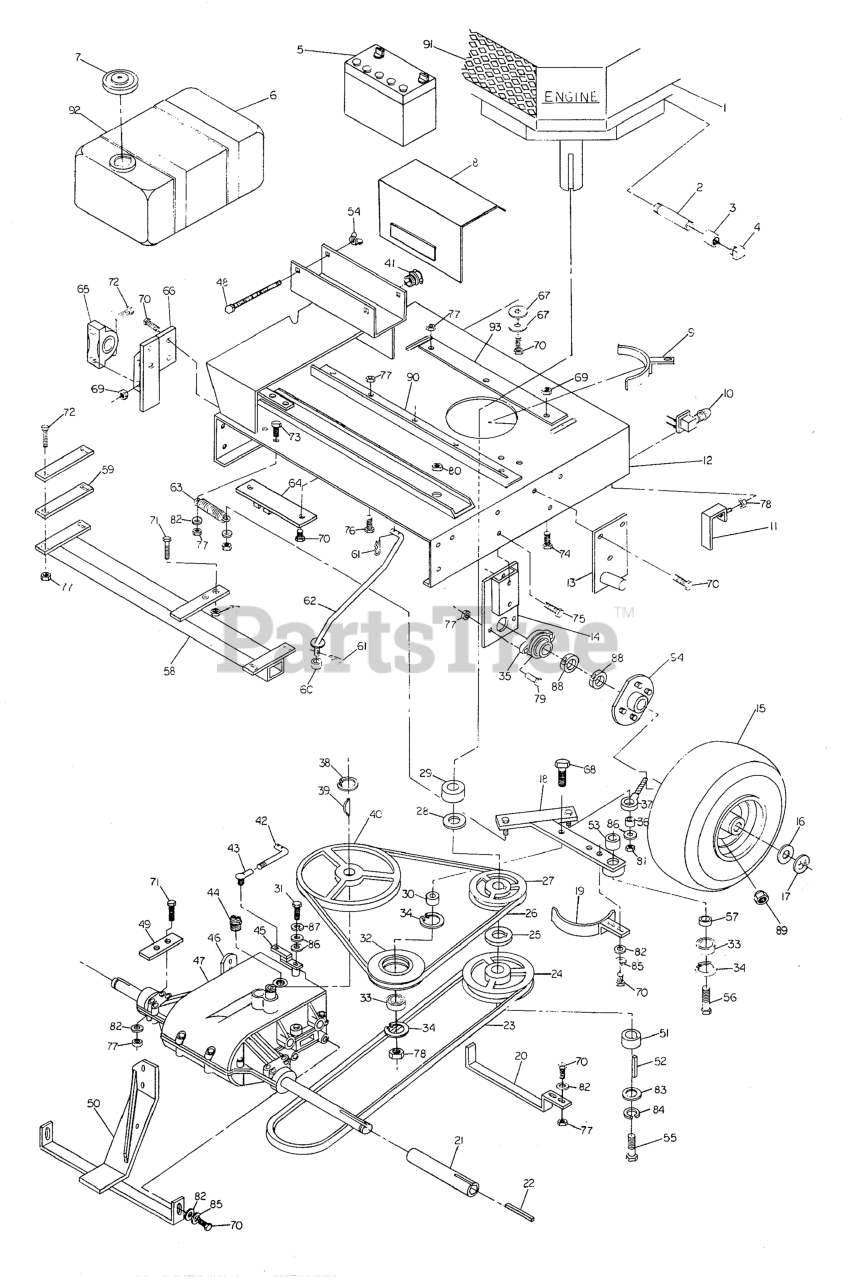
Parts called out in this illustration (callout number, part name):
1	ENGINE, 18HP Briggs & Stratton
2	Oil Drain Extension Kohler 5"
2	Oil Drain Extension
3	Coupler
4	Pipe Plug
5	BATTERY, 11U1L, 350 CCA
6	Fuel Tank, 4 Gallon
7	Gas Cap
8	Battery Cover
9	ENGINE BELT GUIDE
10	Safety Switch
11	Engine Deck Belt Keep Weldment
12	Engine Deck Weldment
13	Pivot Bracket - LH
14	Long Axle Bearing Mount Weldment
15	Drive Tire Assembly (Tire & Rim)
15	Tire Only
15	Rim Only
15	DRIVE HUB
16	SHIM
17	C-CLIP
18	Idler Arm Weldment
19	Idler Pulley Belt Guide
20	Belt Guide
21	Long Axle Support
22	KEY, 3/16" SQ. X 2-1/2
23	BELT, B Section
24	ENGINE PULLEY
25	1/8" Spacer
26	Belt A Section
27	ENGINE PULLEY
28	SHIM, 1.0 X 1.5 X 0.125
29	Engine Spacer
30	SPACER, Shoulder
31	1/4-28 x 5/8 Bolt
32	Idler Pulley Clutch
33	BEARING, BALL 11/16X1-9/16X15/32
34	SNAP RING, Internal
35	Bearing
36	Cable Spacer
37	Clutch Cable
38	RING, External, Snap
39	Hy Pro Key
40	Transaxle Pulley
41	Connector
42	Shifting Linkage
43	BALL JOINT, 3/8" Female Studded
44	Neutral Safety Switch
45	Shifting Lever
46	Brake Lever
47	Transaxle
48	5/16-18 x 6 Carriage Bolt
49	Transaxle Support Spacer
50	Transaxle Support Weldment
51	SPACER, .63 x 1.00 x .63
52	KEY, 1/4 SQ. X 3
53	SPACER, .50 x 1.00 X .69
54	5/16-18 Wing Nut
56	1/2-20 2-1/4 GD 5 Bolt
57	INSERT, Bearing
58	Transaxle Support Weldment
59	Transaxle Support Spacer
60	SLEEVE
61	HAIRPIN CLIP
62	Linkage Arm Weldment
63	SPRING, Extension
64	Brake Cable Mount Weldment
65	Pillow Block Bearing
66	Short Axle Support Weldment
67	5/16 Fender Washer
68	3/8-16 x 1-3/4 GD 5 Bolt
69	5/16-18 Nylon Lock Nut
70	5/16-18 X 1 GD 5 Bolt
71	5/8-18 x 2-3/4 GD 5 Bolt
72	5/16-18 x 1-1/2 GD 5 Bolt
73	5/16-18 X 1-3/4 GD 5 Bolt
74	5/16-18 X 1-3/4 Carriage Bolt
75	3/8-16 x 2 GD 5 Bolt
76	5/16-18 x 2 GD 5 Bolt
77	5/16-18 Serrated Flange Nut
78	3/8-16 Nylon Nut
79	5/16-18 x 1-1/4 Gd 5 Bolt
80	1/2-20 Nylon Lock Nut
81	1/4-20 Nylon Lock Nut
82	5/16 Flat Washer
83	7/16 Flat Washer
84	7/16 Lock Washer
85	5/16 Lock Washer
86	1/4 Flat Washer
87	1/4 Lock Washer
88	COLLAR, 1" Split
89	LUG NUT, 1/2-20
90	Front Engine Deck Support
91	Muffler Guard
92	Gas Tank Strap
93	Kohler Engine Deck Support Rear
93	Rear Engine Deck Support B & S
94	DRIVE HUB
